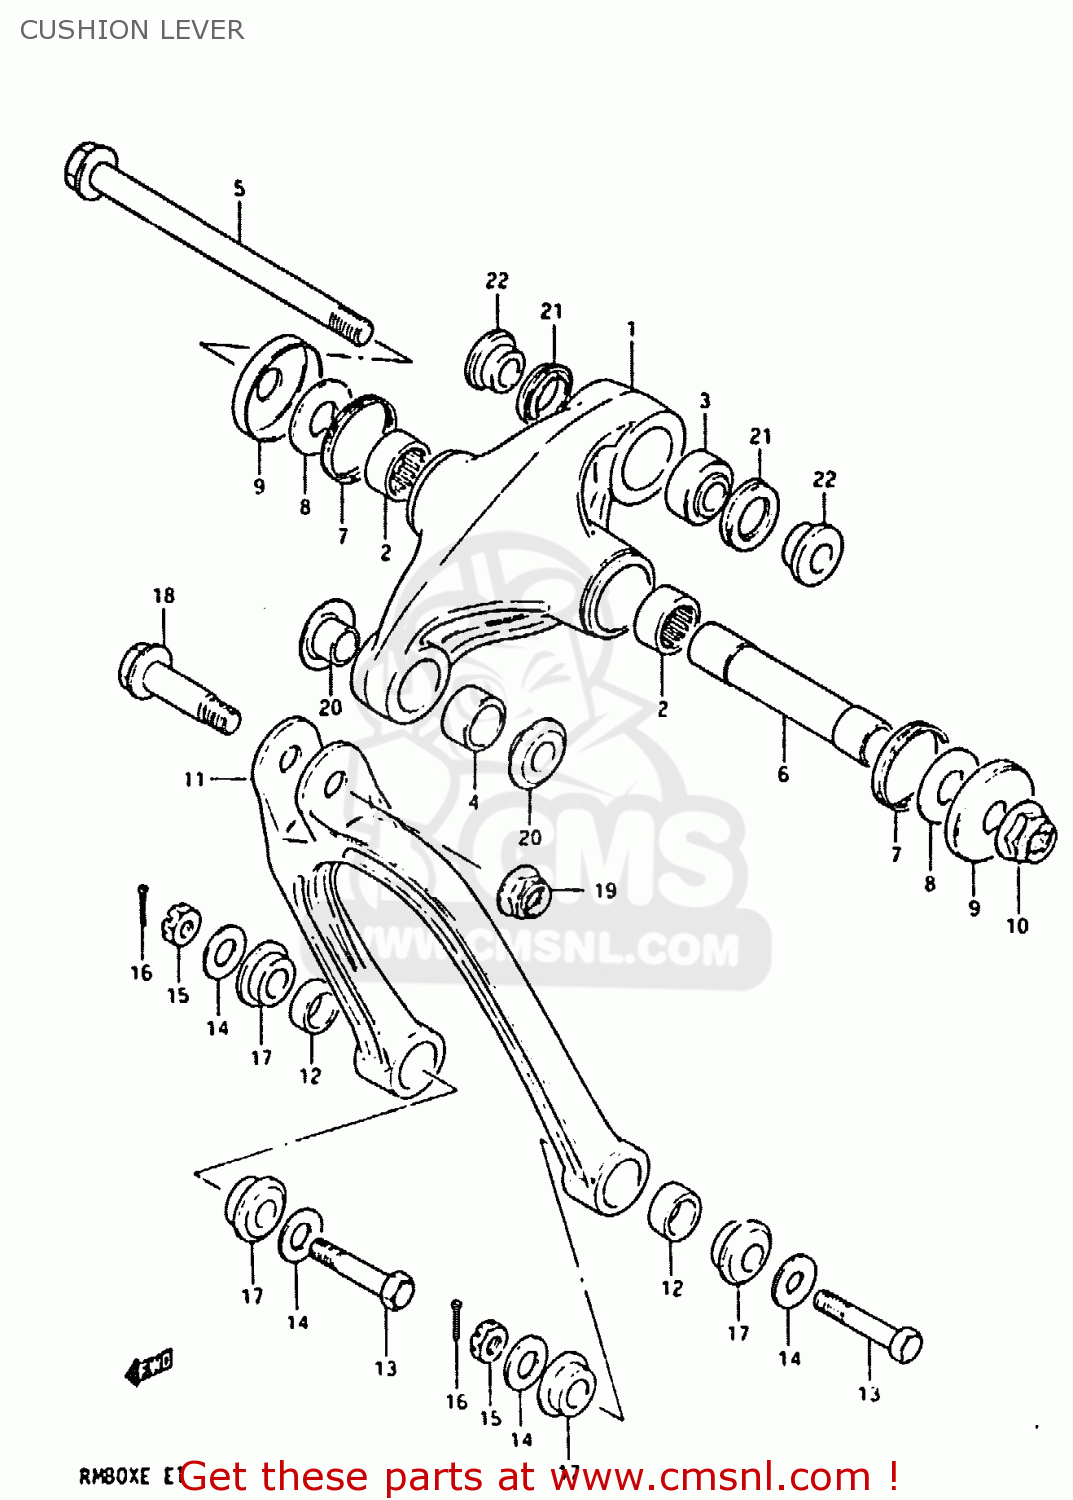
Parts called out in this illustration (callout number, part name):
1	LEVER SET,REAR CUSHION
2	BEARING(17X25X20)
3	BEARING
4	BUSH,FR
5	SHAFT,REAR CUSHION LEVER
6	SPACER,REAR CUSHION LEVER
7	DUST SEAL,RR CUSHION LEVER
8	WASHER
9	DUST COVER,REAR CUSHION
10	NUT 12MM
11	ROD SET,REAR CUSHION LEVER
12	BUSHING
13	BOLT,REAR CUSHION LEVER
14	WASHER
15	NUT 8MM
16	PIN 20X20
17	SPACER,REAR CUSHION ROD
18	BOLT(10X44)
19	NUT
20	SPACER,REAR CUSHION,FRONT
21	DUST SEAL,REAR CUSHION,LEFT
22	SPACER
